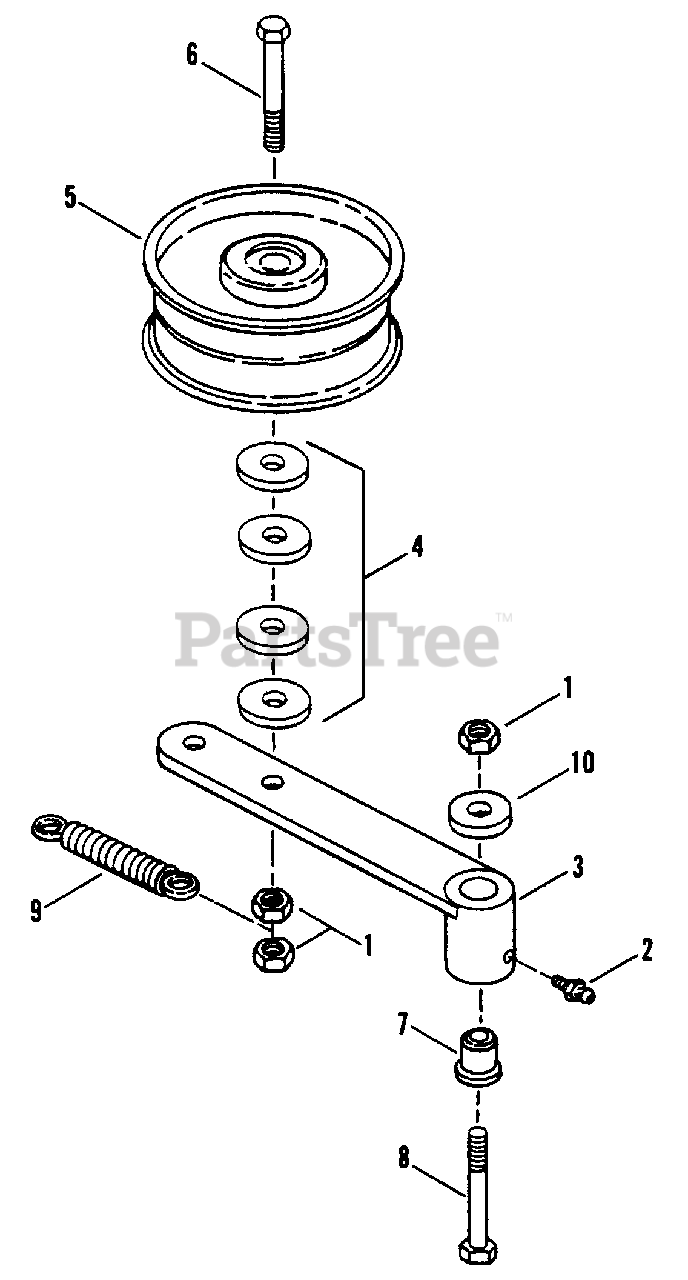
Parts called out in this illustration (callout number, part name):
1	NUT, 3/8-16 Nyloc
2	ZERK, 1/4-28
3	IDLER WELDMENT
4	WASHER, 3/8" Flat
5	PULLEY, Idler
6	SCREW, 3/8-16 x 2 1/2" Hex Head
7	SPACER, Pivot
8	SCREW, 3/8-16 x 3 1/4" Hex Head
9	SPRING, Idler Tension
10	BUSHING, 14 Gage Spacer
